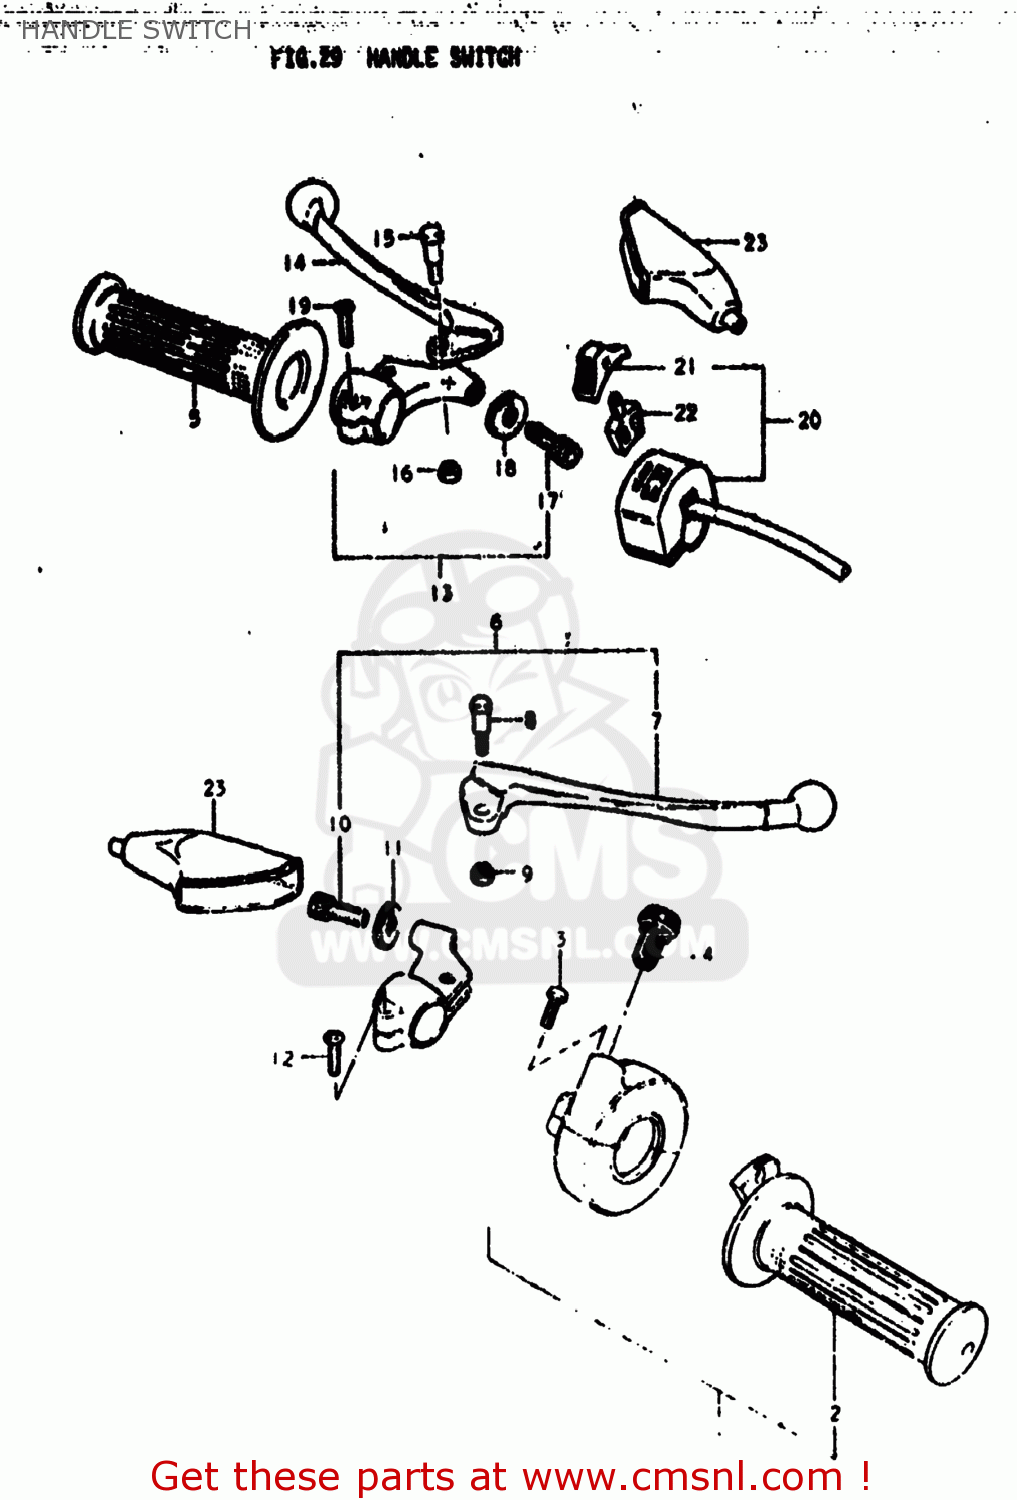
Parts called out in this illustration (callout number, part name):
1	GRIP ASSEMBLY,THROTTLE
2	GRIP,THROTTLE
3	SCREW
5	GRIP,LEFT
6	LEVER ASSY,BRAKE
7	LEVER,BRAKE
8	BOLT,LEVER
9	NUT 6MM
10	ADJUSTER,CABLE
11	NUT,CABLE ADJUSTER
12	SCREW
13	LEVER ASSY,CLUTCH
14	LEVER,CLUTCH
15	BOLT,LEVER
16	NUT 6MM
17	ADJUSTER,CABLE
18	NUT,CABLE ADJUSTER
19	SCREW, 6X20
20	SWITCH,DIMMER
21	KNOB,LIGHTING & DIMMER
22	BLOCK,LIGHTING/DIMMER
23	COVER,CLUTCH LEVER
